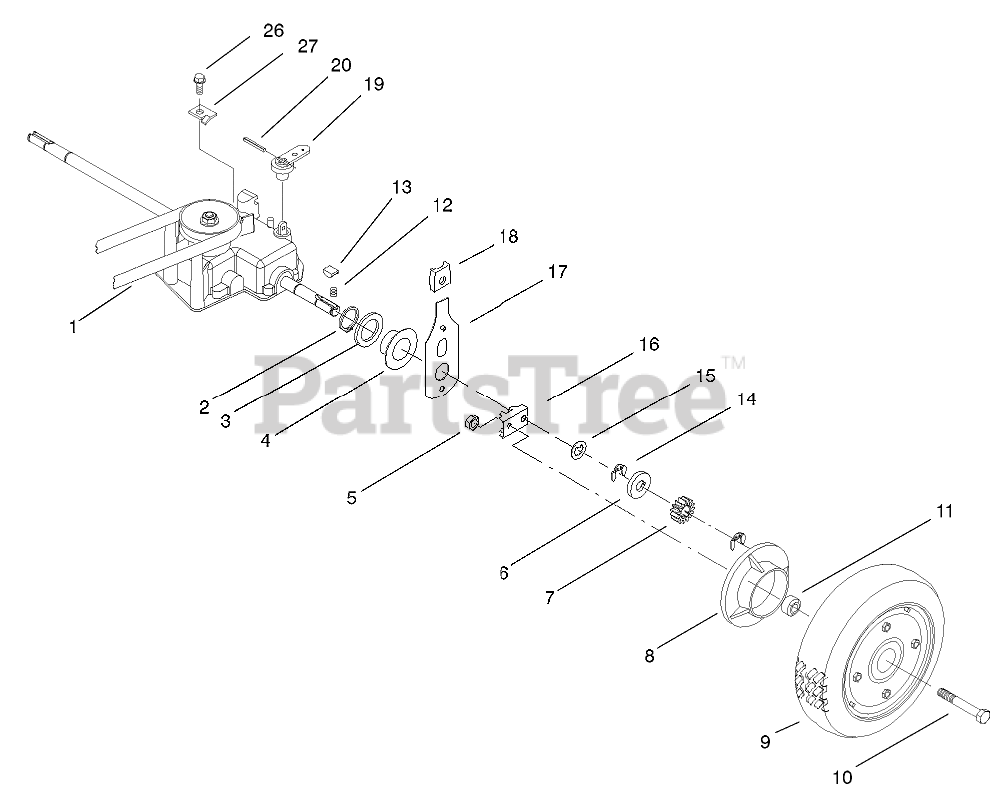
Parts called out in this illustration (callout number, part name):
1	V-BELT
2	RING-RETAINING
3	WASHER
4	CAP-END
5	NUT-LOCK, CONE
6	WASHER-THRUST, OUTER
7	GEAR-PINION
8	COVER-WHEEL
9	WHEEL AND TIRE ASM
10	SCREW-HH
11	SPACER-COVER, WHEEL
12	SPRING-COMPRESSION
14	RING-RETAINING
15	WASHER-THRUST, OUTER
16	PIVOT ARM ASM
17	REAR SPRING ARM ASM
18	KNOB-ARM
19	LEVER-SHIFT
20	PIN-COIL
26	SCREW-HWHTF
27	CLAMP-CABLE
